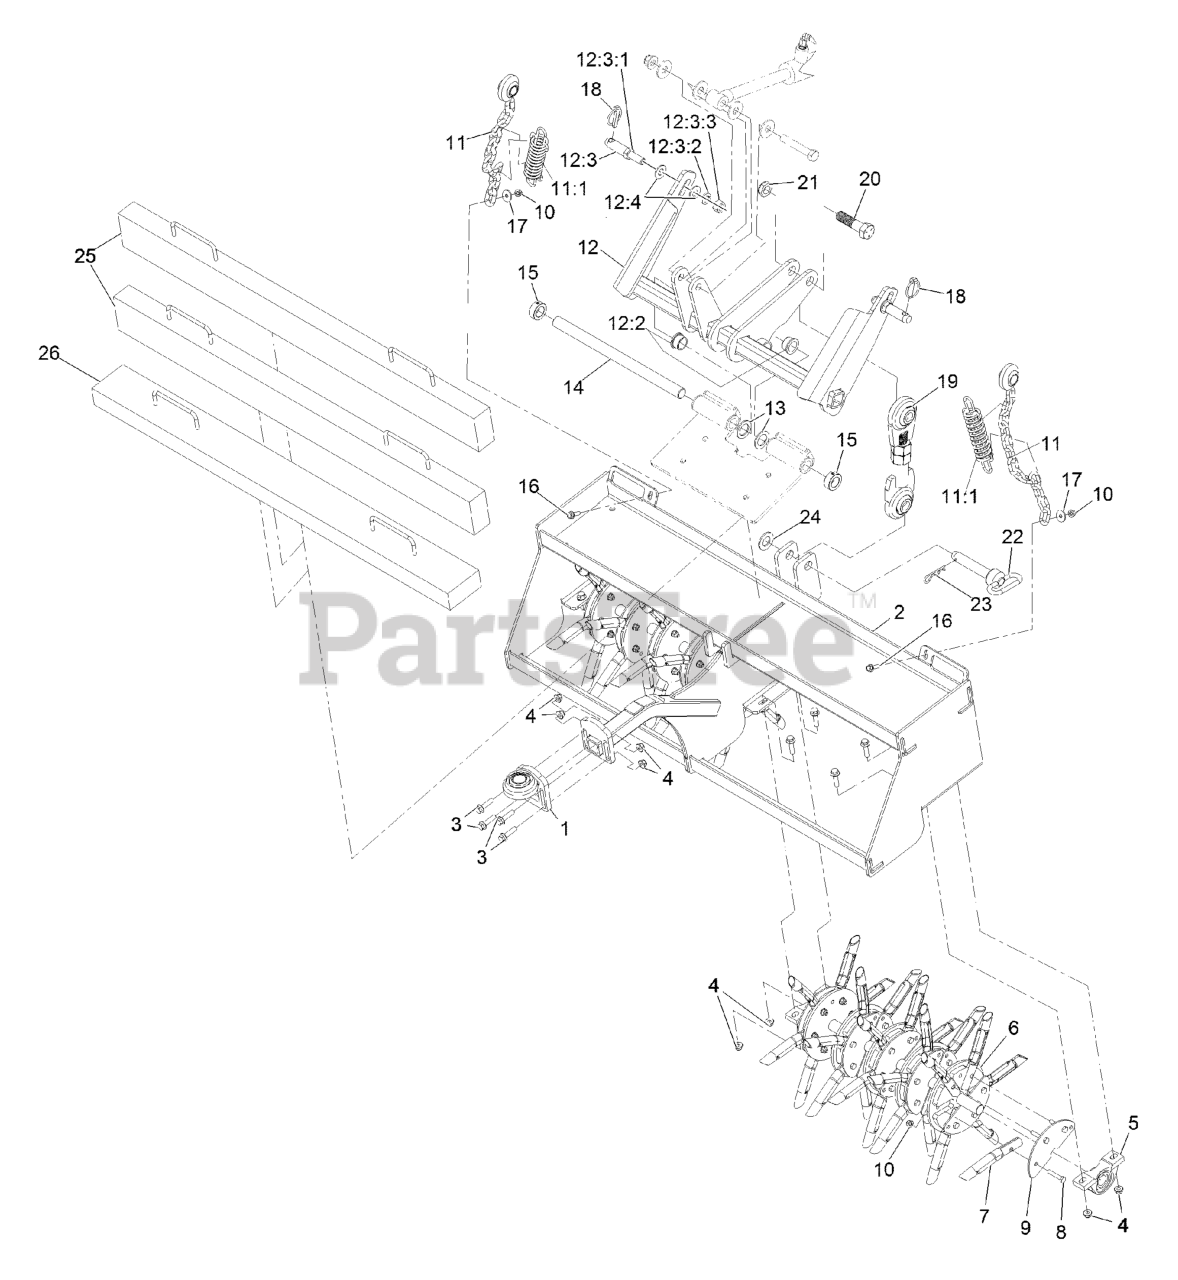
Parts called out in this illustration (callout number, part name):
1	MOUNT-SWIVEL BRG,AER HEAD
2	HEAD-AERATION, 40""
3	SCREW-HHF
4	NUT-HF, NI
5	PILLOW BLOCK BEARING
6	REEL-TINE
7	TINE-CORING (3/4 INCH)
8	SCREW-HH
9	DISK, HALF, AE
10	NUT-HF, NI
11	SWIVEL-CHAIN ASM
11:1	Z-PLUG DRAWBAR SPRING
12	ARM-LIFT, ASM
12:2	BUSHING-FLANGE
12:3	7/8 X 4-1/2 LIFT PIN\N21
12:3:1	NUT-JAM
12:3:2	WASHER-LOCK
12:3:3	NUT-HEX
12:4	WASHER-FLAT
13	WASHER-THRUST
14	PIVOT-LIFT ARM
16	SCREW-HH
17	WASHER-FLAT
18	PIN-LYNCH
19	BALL SWIVEL, ADUSTABLE LI
20	7/8-9 X 3-1/4 GR8 HEX CAP
21	NUT-LOCK, NI
22	7/8 X 4 HITCH PIN RED HAN
23	PIN-HAIR
24	WASHER-FLAT
25	112LBS WEIGHT\N45.25
26	WEIGHT-HORIZ, ZPLUG
